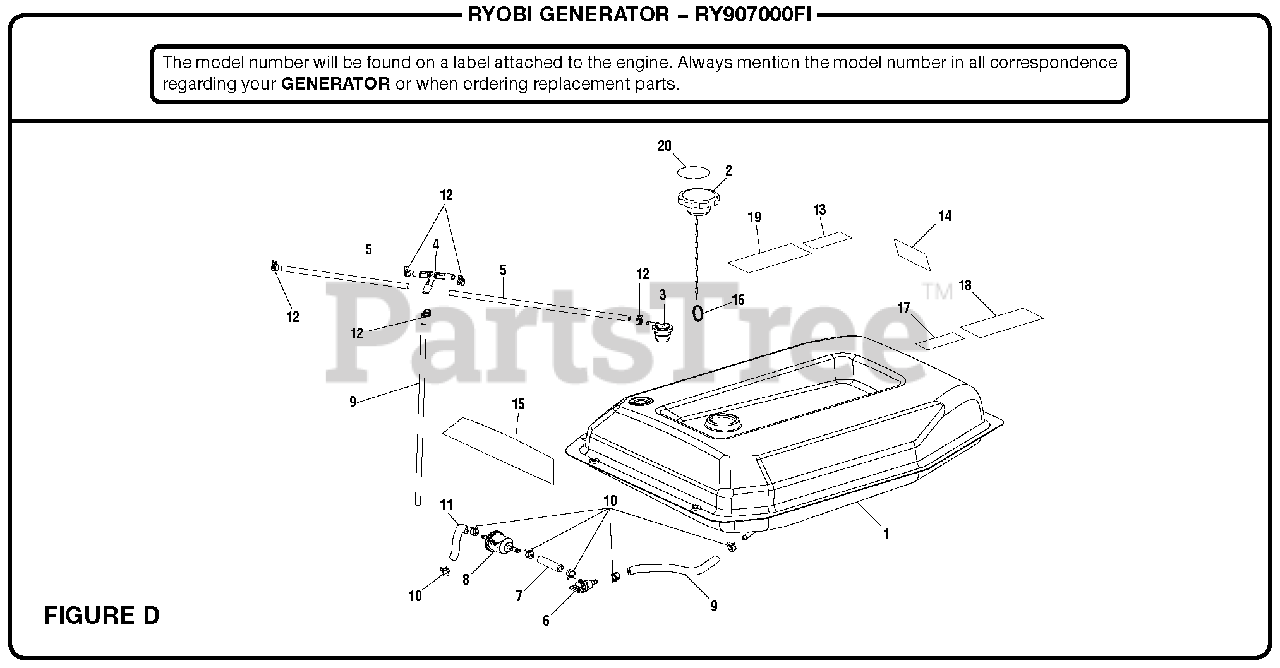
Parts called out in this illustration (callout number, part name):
1	Fuel Tank
3	Vapor Vent
4	Vapor Hose Tee Fitting
5	Vapor Hose (300 mm)
6	Fuel Shut Off Valve
7	Fuel Hose (60 mm)
8	Fuel Filter
9	Fuel Hose (135 mm)
10	Hose Clamp (1/2 in.)
11	Vapor Hose (500 mm)
12	Hose Clamp (3/8 in.)
13	E85 Label
14	Fuel Hose (210 mm)
15	Returnline Fuel Pump
16	Ring Clip
17	Fuel Stabilizer Label (French/Spanish)
18	CPSC Label
19	Warning Label
20	Fuel Stabalizer Danger
